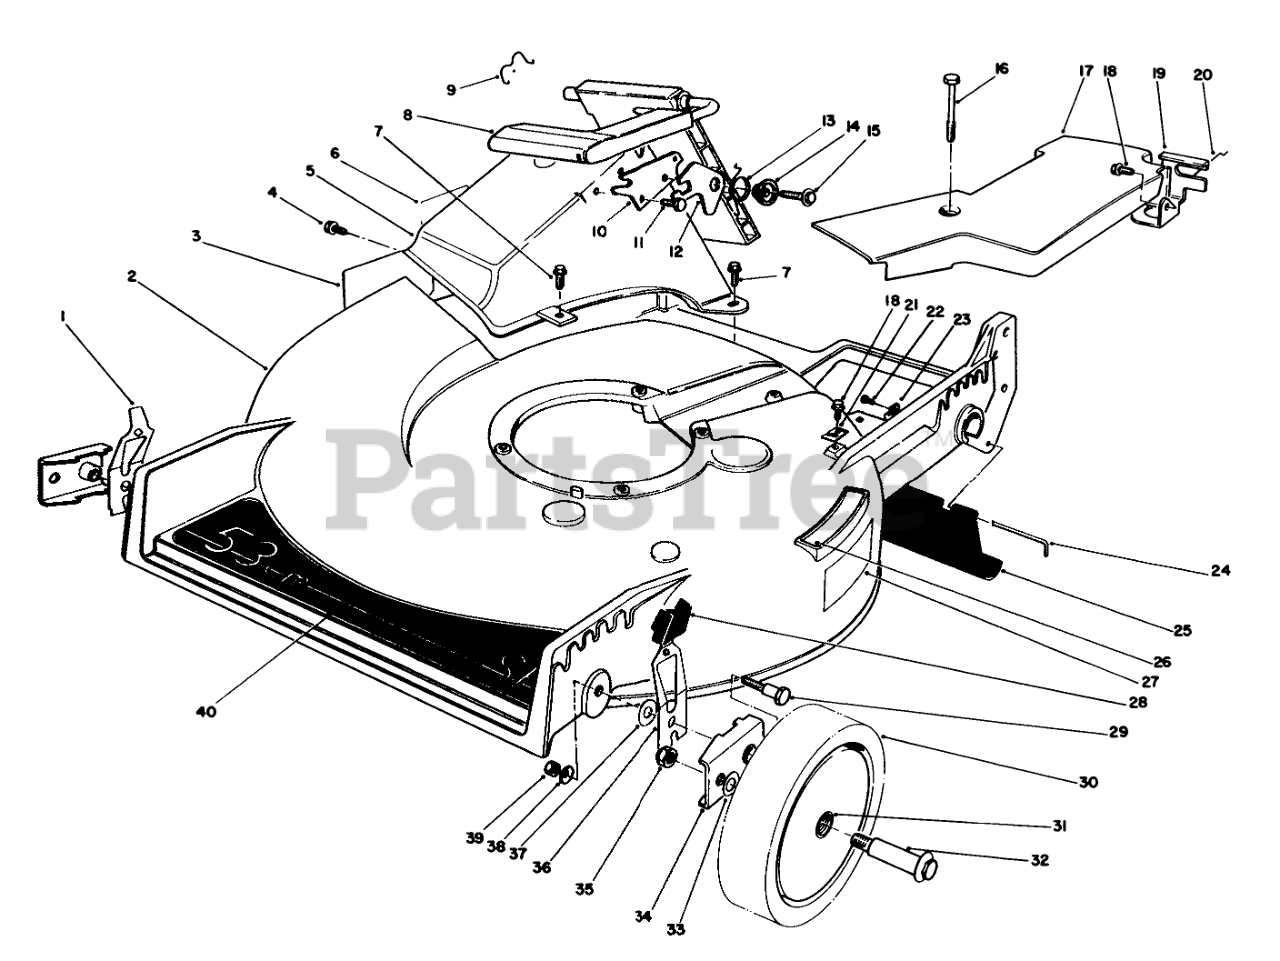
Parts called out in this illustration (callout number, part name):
1	R HP SPRING ARM ASM
2	Housing (Incl. Ref. #3, 26 & 27)
3	DECAL-DANGER
4	SCREW AND WASHER ASM
5	Tunnel-Discharge (Incl. Ref. #6)
6	DECAL - DANGER
7	SCREW-HWH
8	Discharge Door Assembly
9	DOOR RET SPRING
10	DOOR LATCH PLATE
11	SCREW-PLASTITE
12	SAFETY LATCH
13	TORSION SPRING
14	DOOR SPACER
15	SCREW-HWH
16	SCREW-HHFTF
17	Cover-Belt
18	SCREW-HWHTF
19	Bracket-Traction Adj.
20	RETAINER-CABLE
21	CLAMP-CABLE
22	SCREW
23	CLAMP-CABLE
24	ROD-SHIELD
25	SHIELD-TRAILING
26	DECAL - STEP PAD INT'L
27	Decal Danger
28	KNOB-ARM
29	PIVOT SCREW
30	Wheel & Tire Assembly (Incl. Ref. #31)
31	BUSHING
32	BOLT-WHEEL
33	WASHER
34	HP PIVOT ARM ASM
35	Nut
36	L. HP SPRING ARM ASM
37	WASHER-PIVOT
38	WASHER-BELLEVILLE
39	NUT-LOCK, NI
40	DECAL - 53 SP DECK
